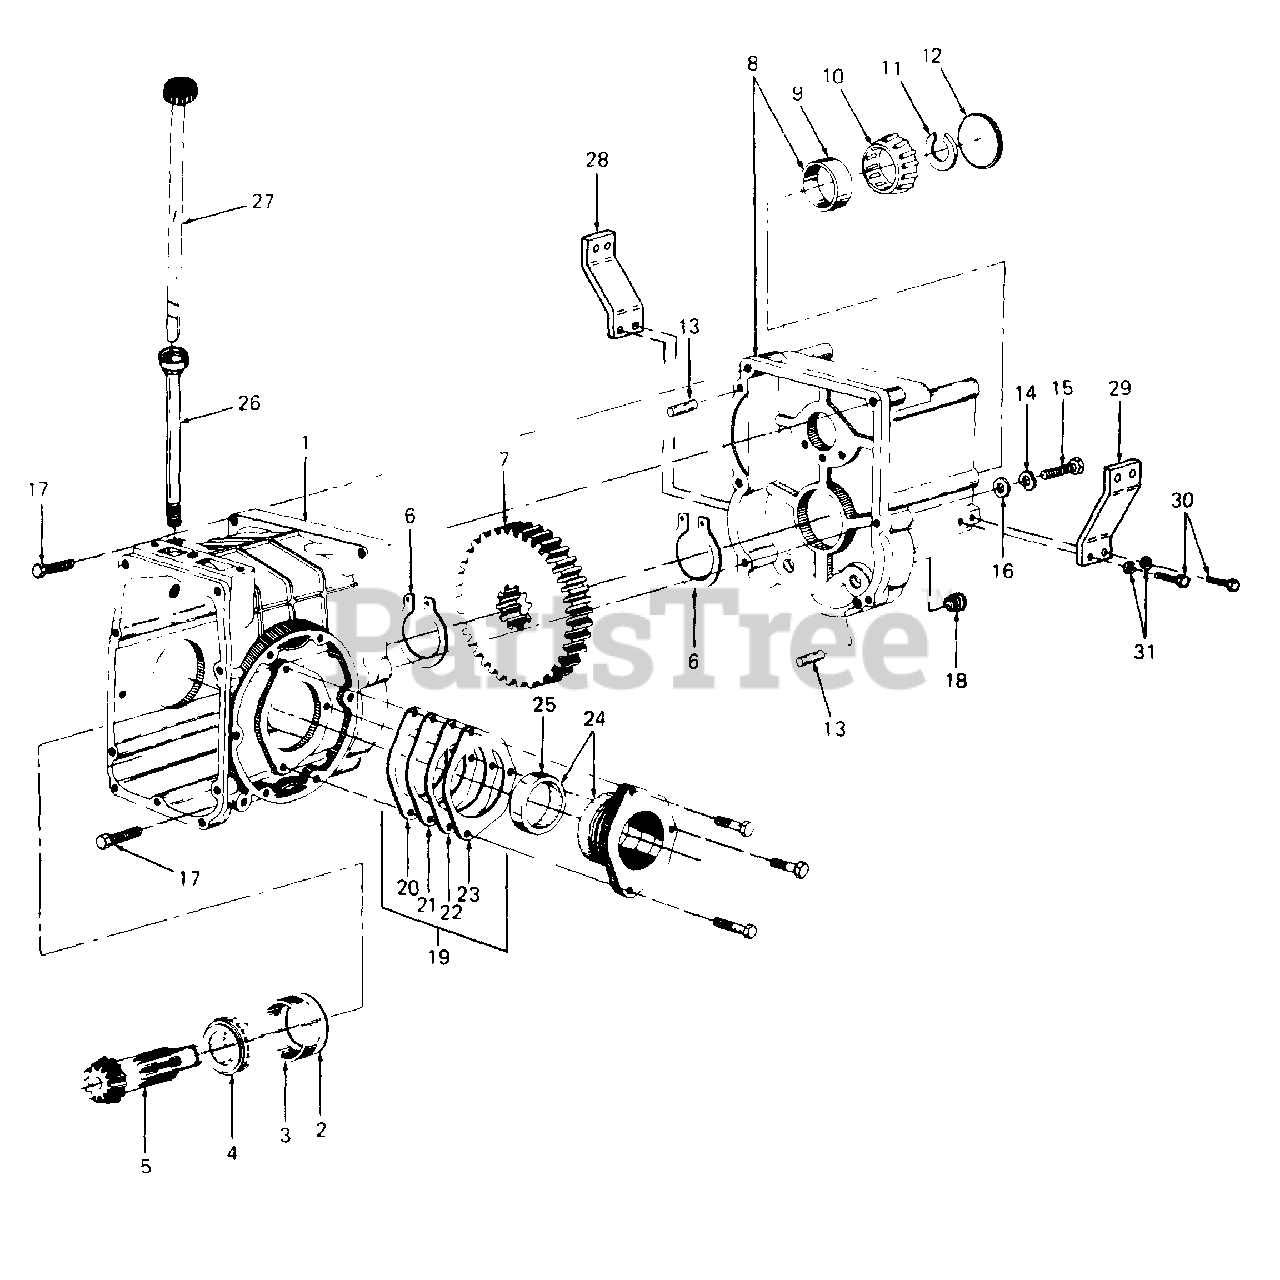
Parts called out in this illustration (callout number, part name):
1	Housing Assy, Rear Transaxle
2	Shim, Rear Bearing Cup, .004 Thk
3	Cup, Roller Bearing
4	Cone, Roller Bearing
5	Shaft, Bevel Pinion
6	Ring, Retaining, 1.312 Dia
7	Gear, Reduction - 68T
8	Housing Assy, Adapter w/Cup
9	Cup, Roller Bearing
10	Cone, Roller Bearing
11	Retainer Front Bearing, .125 Thk
12	Plug, Expansion, 2.12 OD
13	Pin, Dowel, 3/8 Dia X 5/8 Lg
14	Washer, Spring, .445 X .75 X .017 Thk
15	Screw, Hex Cap, 7/16-14 X 2.5 Lg GR5
16	Washer, Flat, .46 X .875 X .060 Thk
17	Bolt, Hex Patch, 7/16-14 X 1.75 Lg GR5
18	Plug, Drain
19	Shim Package
20	Shim, Bearing Retainer, .004 Thk
21	Shim, Bearing Retainer, .007 Thk
22	Shim, Bearing Retainer, .014 Thk
23	Shim, Bearing Retainer, .028 Thk
24	Retainer Assy, Bearing w/Cup
25	Cup, Roller Bearing
26	Tube, Dipstick
27	Blade Assy, Dipstick
28	Bracket, Trans Mtg -LH
29	Bracket, Trans Mtg -RH
30	Bolt, Hex Patch, 3/8-16 X 1.0 Lg GR5
31	Washer, Lock, 3/8
